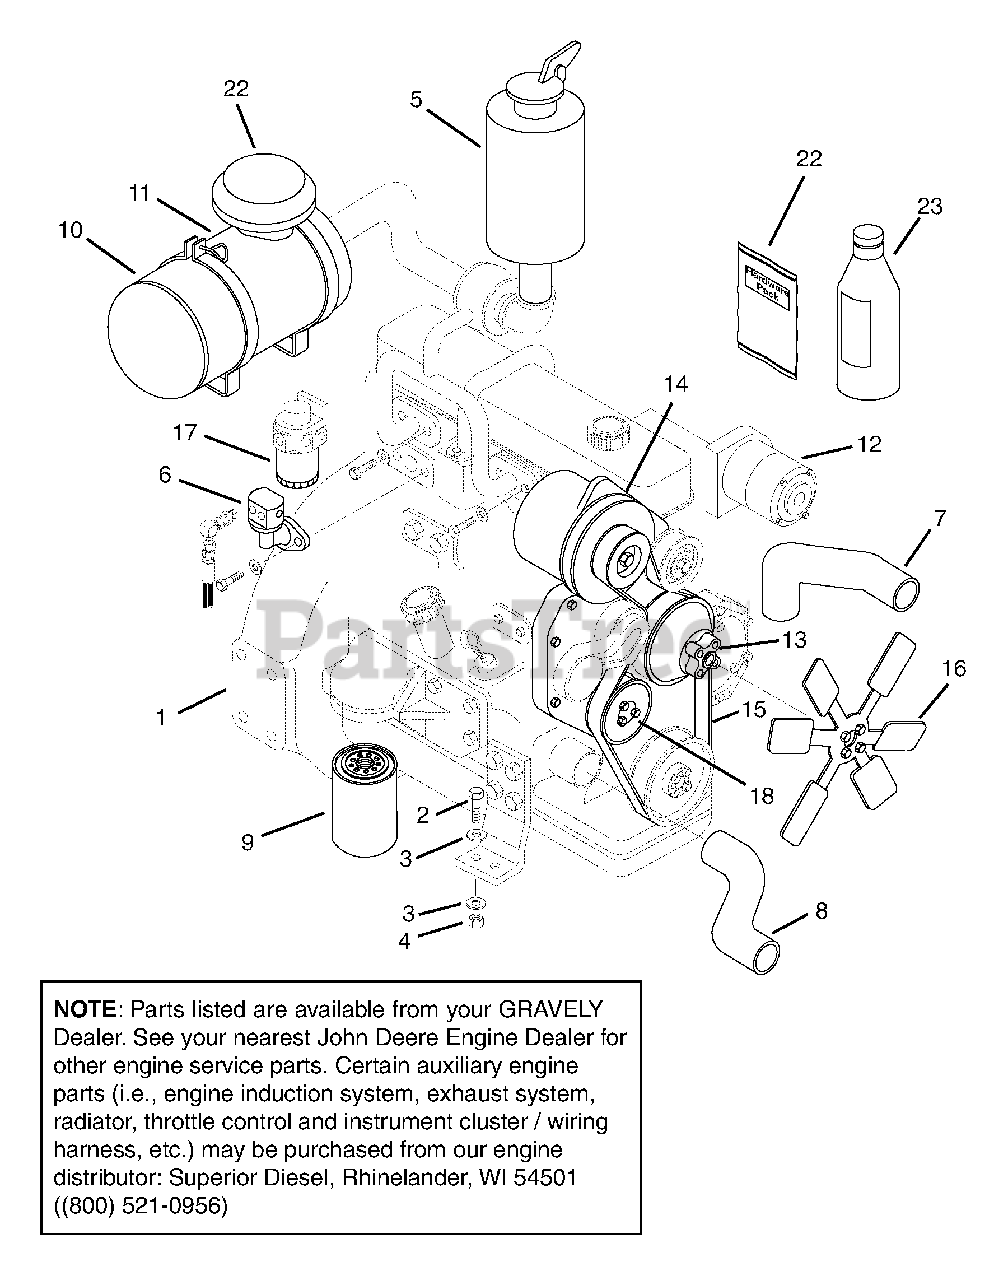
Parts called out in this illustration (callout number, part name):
1	Engine-John Deere 115 HP
2	Bolt-Hex .75-10 x 2.50 Grade 5
3	Washer-Flat-Steel .813 x 2.000 x .148
4	Nut-Locking-Center .75-10
6	Pump-Lift (Fuel)
7	Hose-Radiator-Top
8	Hose-Radiator-Bottom
9	Filter-Oil
10	Filter-Air-Primary
11	Filter-Air-Secondary
13	Pump-Water
13	Gasket, Water Pump
14	Alternator
17	Element-Fuel Filter
18	Pump-Oil
19	Kit-Gasket Overhaul
20	Gasket Set-(Tune-up) (Head Removal)
21	Cap-Air Intake
22	Test Kit-Coolant Conditioner
23	Conditioner-Coolant, 1/2 Gallon
